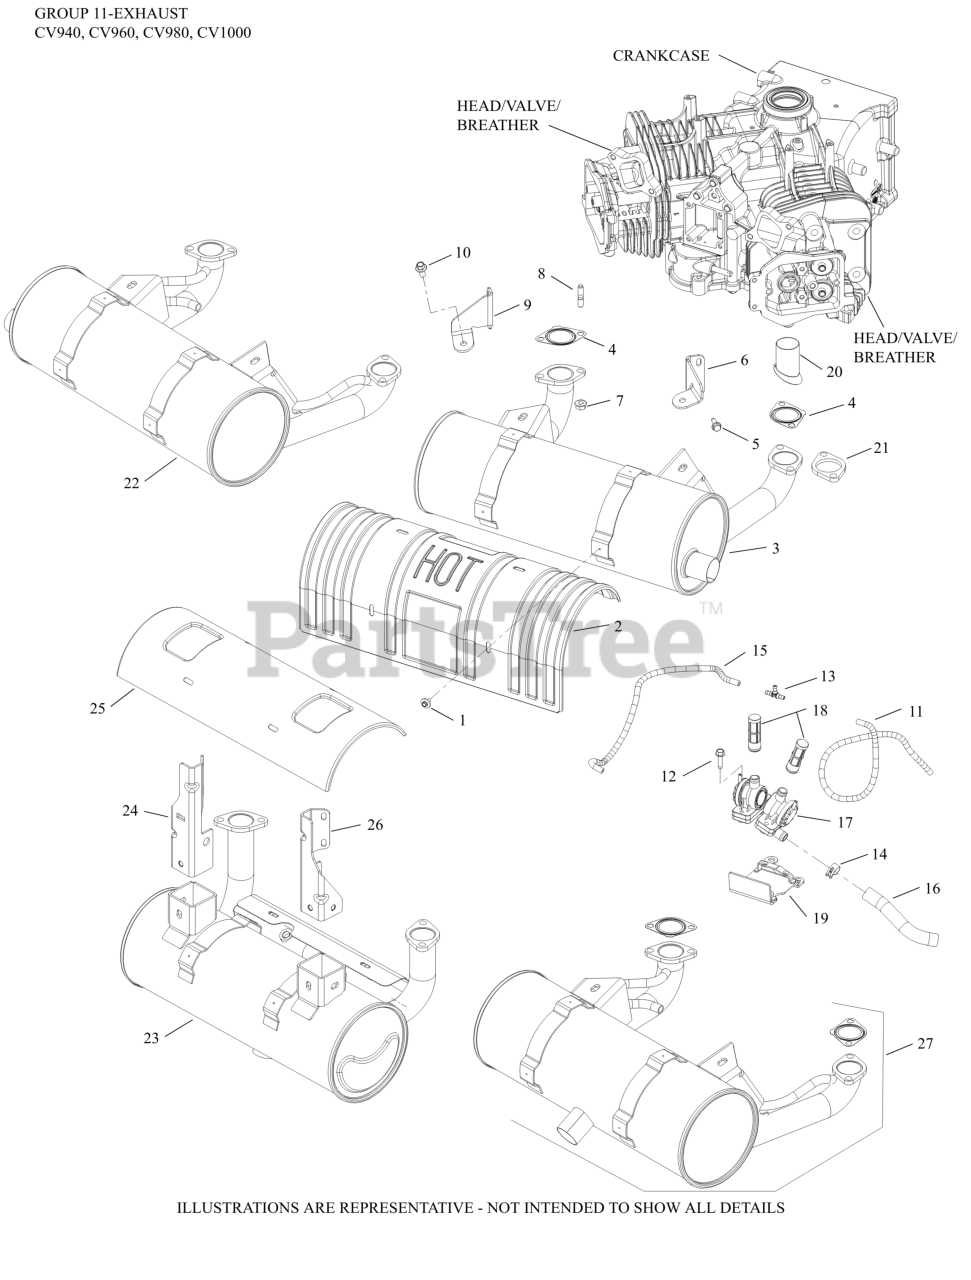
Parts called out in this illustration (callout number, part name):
1	SCREW, SEMS DRILL #8-18X1/2"
2	SHIELD, HEAT
4	GASKET, EXHAUST
5	SCREW, THREAD FORMING
6	BRACKET, MUFFLER CYL #2
7	NUT, FLG M8X1.25
9	BRACKET, MUFFLER CYL #1
10	SCREW, FLG 8X1.25X16
20	LINER, EXHAUST PORT
